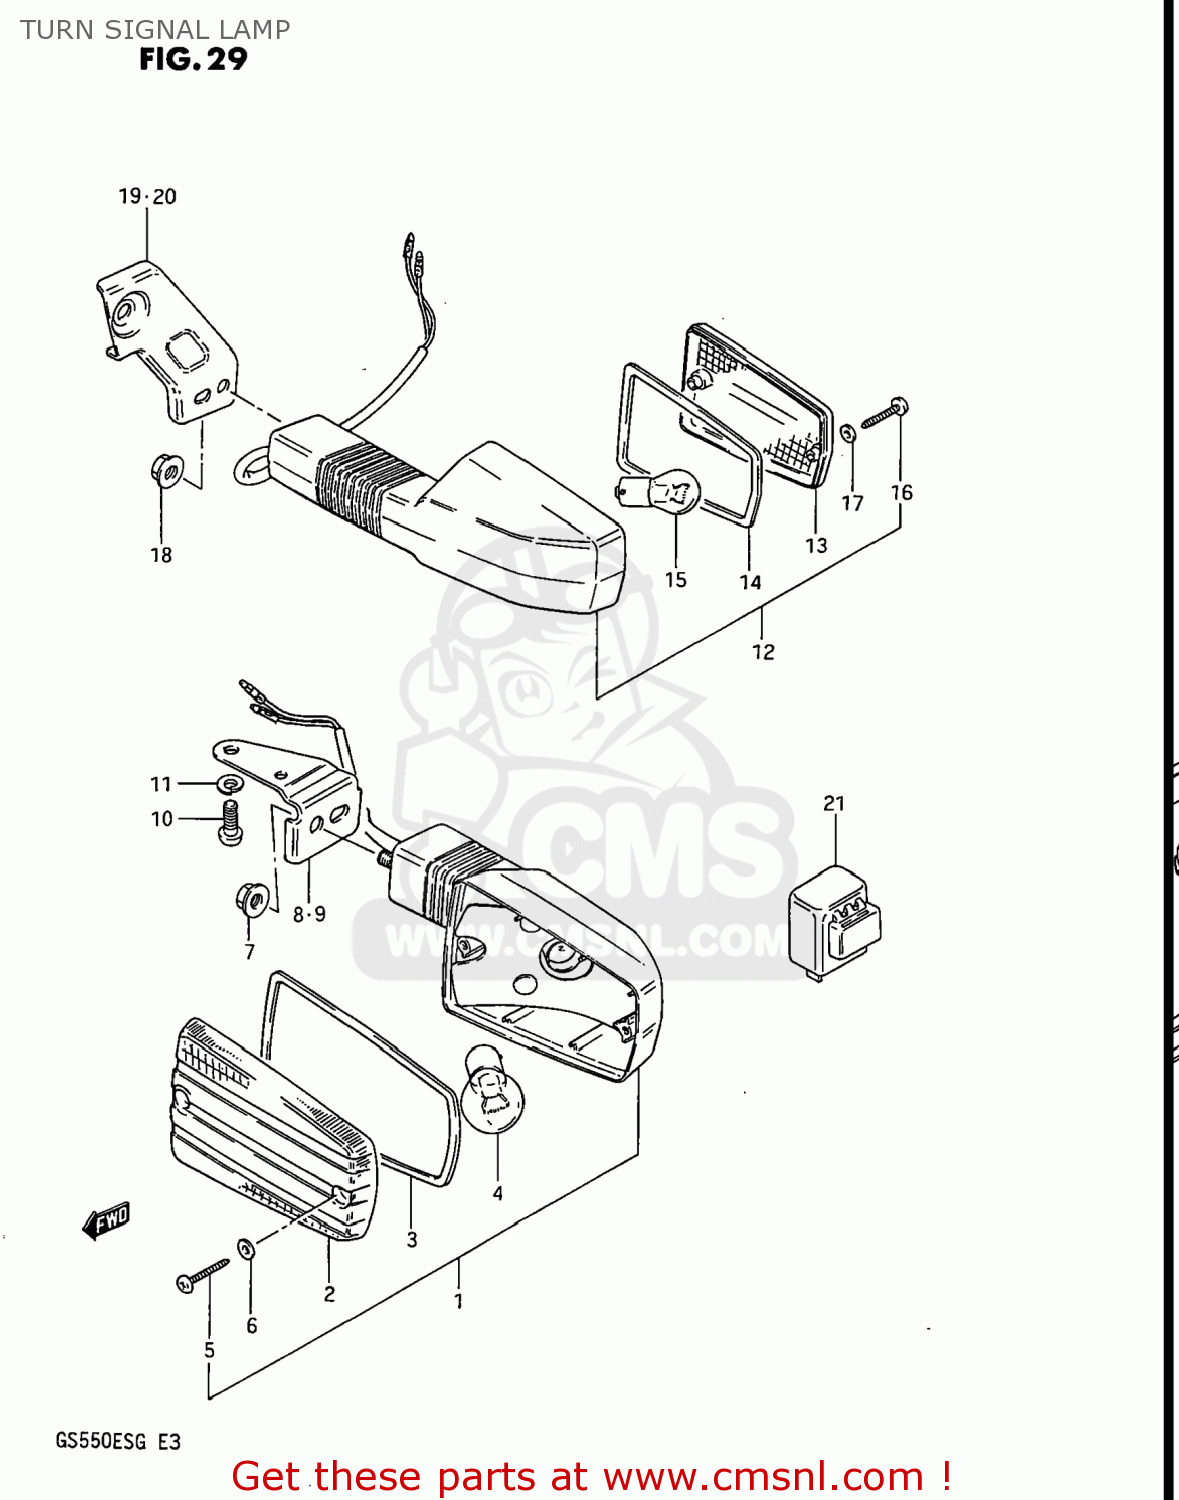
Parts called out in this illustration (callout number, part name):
1	LAMP ASSY,FR TURN SIGNAL
2	LENS,TURN SIGNAL LAMP
3	GASKET (NAS)
4	BULB(12V23W)
5	SCREW
6	GASKET (NAS)
7	NUT M8
8	BRACKET,FRONT TURN SIGNAL
9	BRACKET,FRONT TURN SIGNAL
10	SCREW
11	WASHER,LOCK
12	LAMP ASSEMBLY,FRONT TURN SIGNAL
13	LENS
14	GASKET (NAS)
15	BULB(12V23W,STANLEY,A4577A)
16	SCREW
17	GASKET (NAS)
18	NUT
19	BRACKET,REAR TURN SIGNAL
20	BRACKET,REAR TURN SIGNAL
21	RELAY ASSEMBLY,TURN SIGNAL
